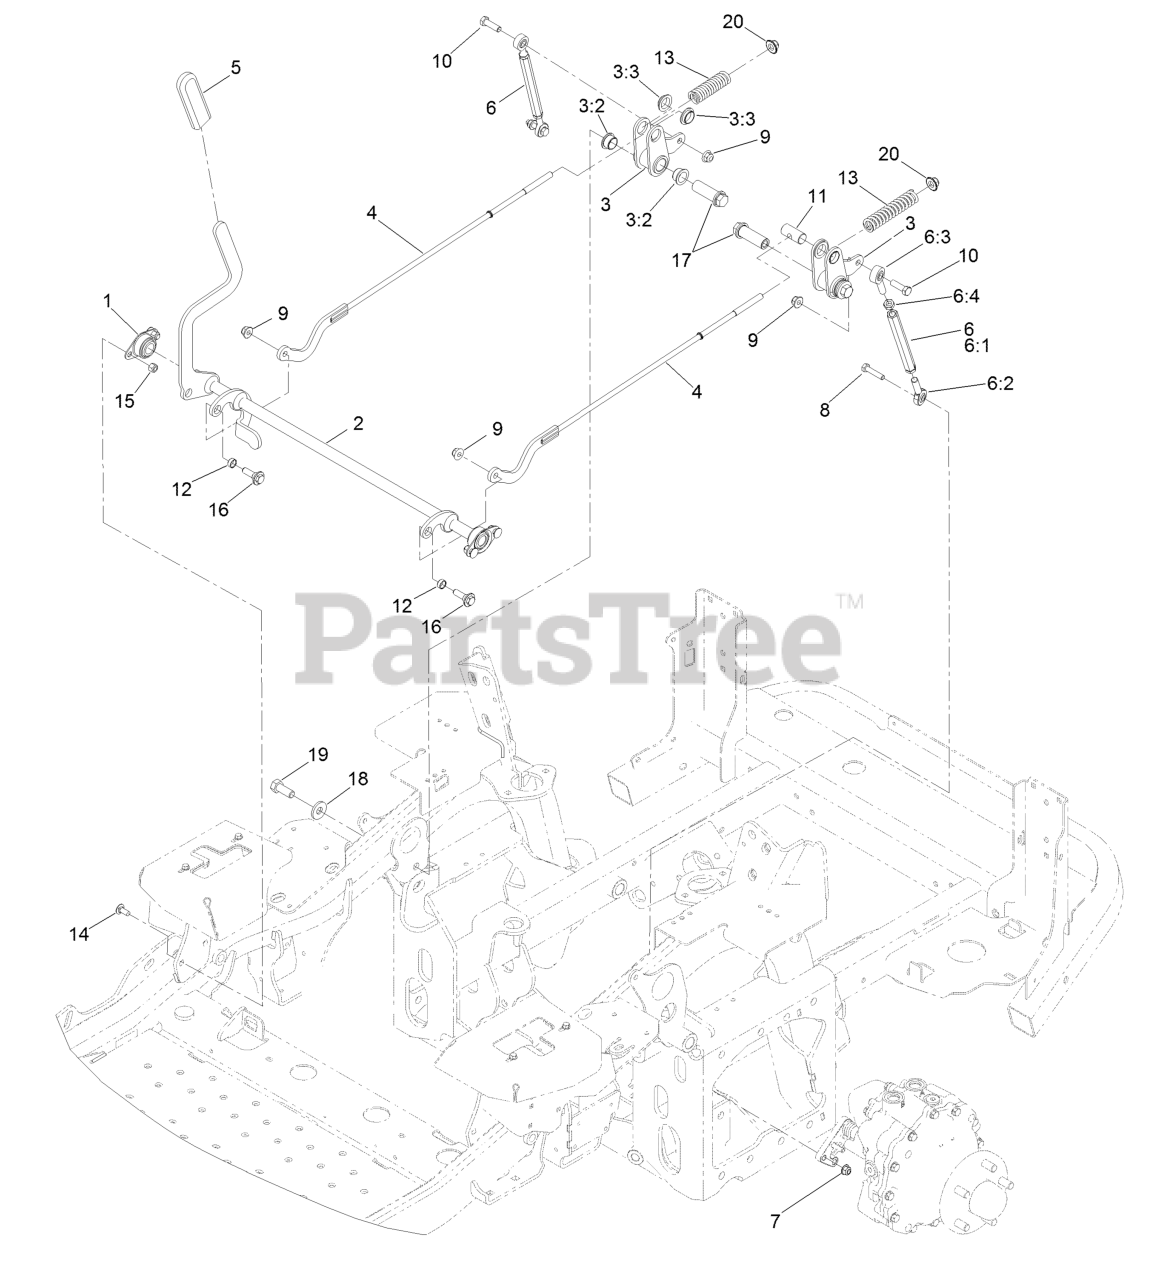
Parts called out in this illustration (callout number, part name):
1	Bearing-Flange, Side
2	Shaft-Brake
3	Brake Bellcrank ASM
3:2	Bushing-Flange
3:3	Bushing-Flange
4	Link-Brake, Upper
5	Grip-Lever
6	Turnbuckle ASM
6:1	Turnbuckle
6:2	Bearing-End, LH Rod
6:3	Balljoint
6:4	Nut-HJ
7	Nut-HF, NI
8	Screw-HH
9	Nut-HF, NI
10	Screw-HH
11	Pin-Trunion
12	Bearing-Sleeve
13	Spring-Compression
14	Screw-CARR
15	Nut-Lock, NI
16	Screw-Shoulder, HWH
17	Hub-Threaded
18	Washer-Spring
19	Screw-HH
20	Nut-Flange, NI
